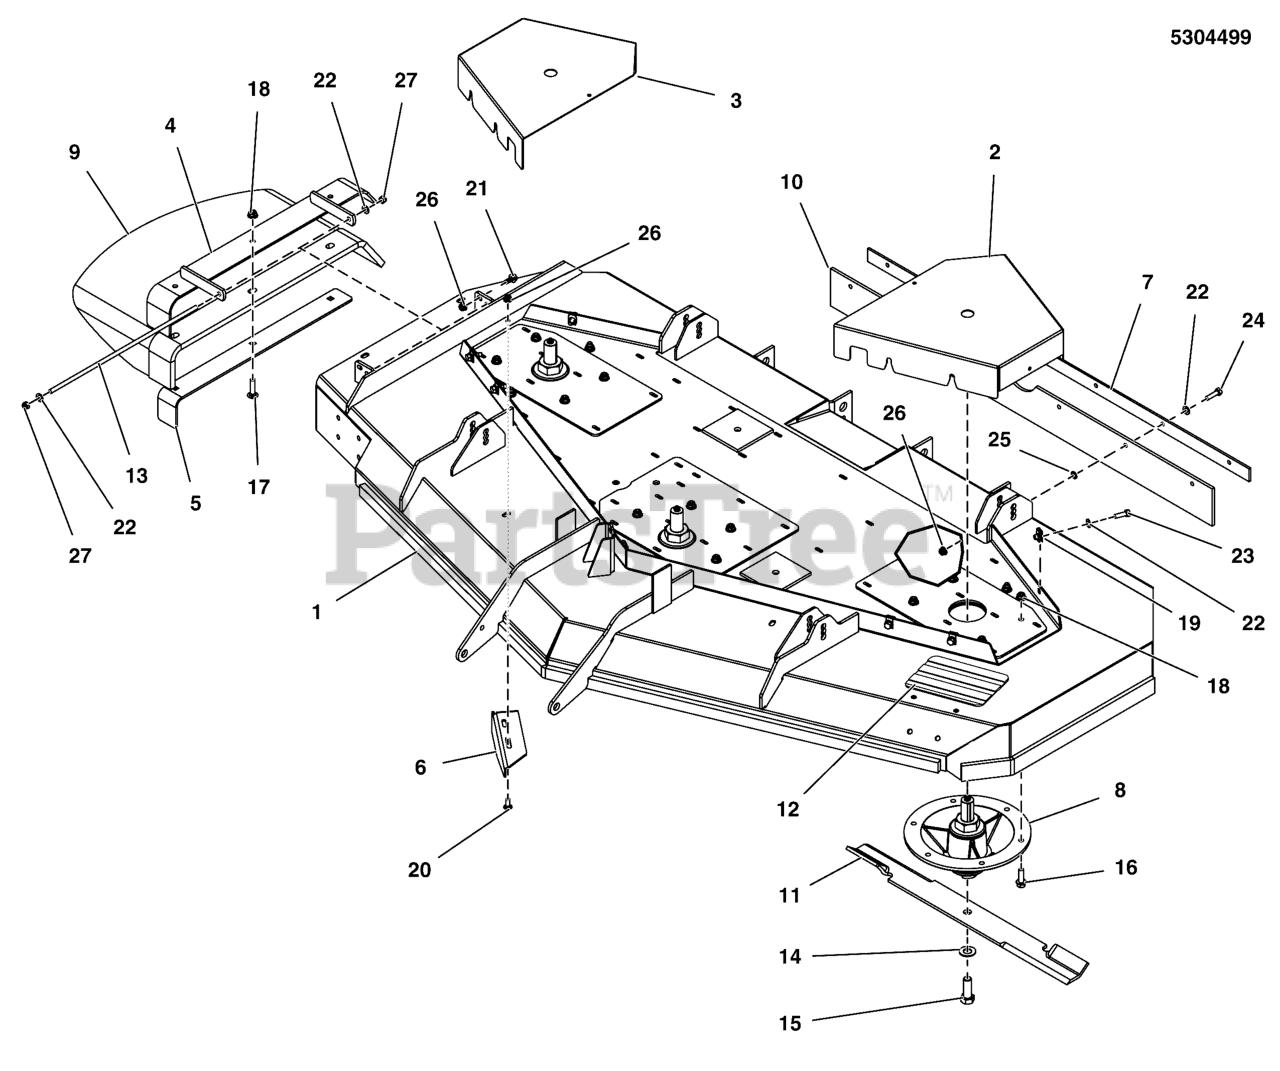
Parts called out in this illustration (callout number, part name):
1	DECK SHELL W/DECALS,72,F320Z,5414880B
2	GUARD, LH, 72 - RED
3	GUARD, RH, 72 - RED
5	SUPPORT, DISCHARGE CHUTE - BLK
6	PLATE, DEFLECTOR, 72 - BLK
7	PLATE, SUPPORT, 72" - BLK
8	SPINDLE ASSEMBLY
9	CHUTE, RUBBER DISCHARGE (5104442)
10	FLAP, STRIPER, 72 DECK
11	BLADE SET, 72 DECK
12	SAFETY WALK, 9.75 X 6.00
13	ROD, MOUNT, CHUTE 61, CZ
14	WASHER, BLADE BOLT, 9/16" F436, CZ
15	BOLT, 5/8-11 X 1-3/4 GD8
16	BOLT, 3/8-16 X 1-1/4, FLANGE, GD 5, CZ
17	BOLT, 3/8-16 X 1-1/2, CARRIAGE, GD5, CZ
18	NUT, 3/8-16 HEX NYLOCK FLANGE
19	BODY CLIP, 5/16-18-7GA MATERIAL
20	BOLT, 5/16-18 X 3/4, CARRIAGE
21	BOLT, 5/16-18 X 3/4 GD5
22	WASHER, 5/16" SAE
23	BOLT, 5/16-18 X 1 GD5 CZ
24	BOLT, 5/16-18 X 1-1/4 GD5 CZ
25	5/16 PUSH-ON NUT RETAINER, STL, CZ
26	NUT, 5/16-18 HEX NYLOCK FLANGE
27	NUT, 5/16-24 HEX NYLON LOCK
